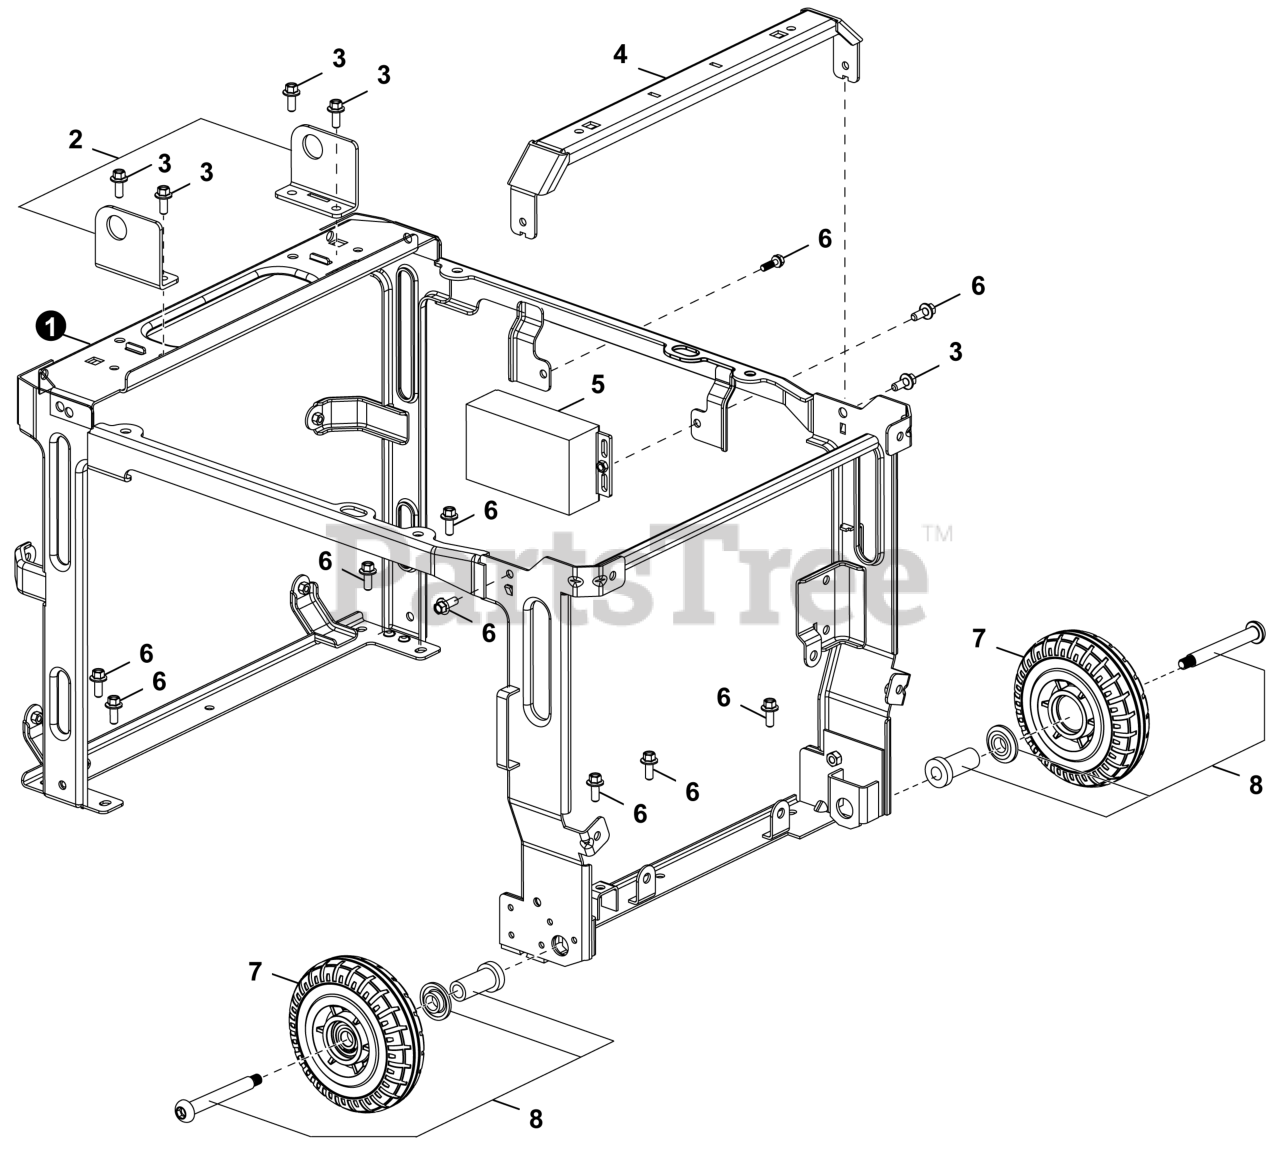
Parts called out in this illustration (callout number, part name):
1	ASSY., FRAME
2	KIT, HANDLE MOUNT
5	CONTROLLER
7	WHEEL, FRONT
8	AXLE, WHEEL
